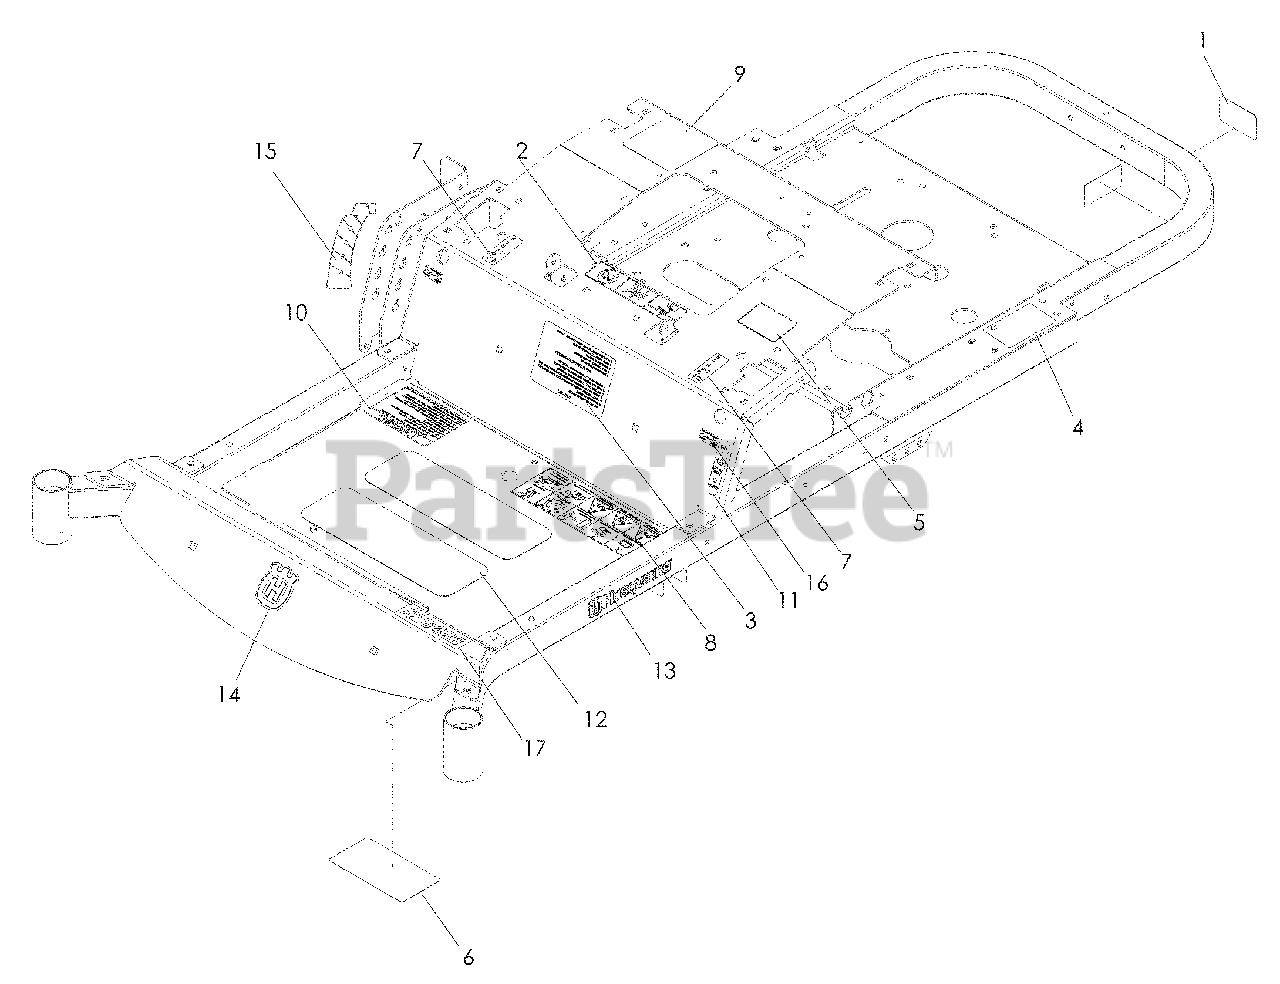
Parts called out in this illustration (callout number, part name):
1	DECAL, PROP 65
2	DECAL, BATTERY WARNING
3	DECAL, START
4	DECAL, DO NOT TOW
5	DECAL, EXIT MOWER
6	DECAL, SERVICE
7	DECAL, MOTION CONTROL
8	DECAL, SAFETY WARN
9	DECAL, RESPONSIBILITY
10	DECAL, WARNING
11	DECAL, PARK BRAKE
12	ABRASIVE PAD
13	DECAL, HUSQVARNA
14	DECAL, CROWN H
15	DECAL, HEIGHT
16	DECAL, FST
17	DECAL, RZ4219
